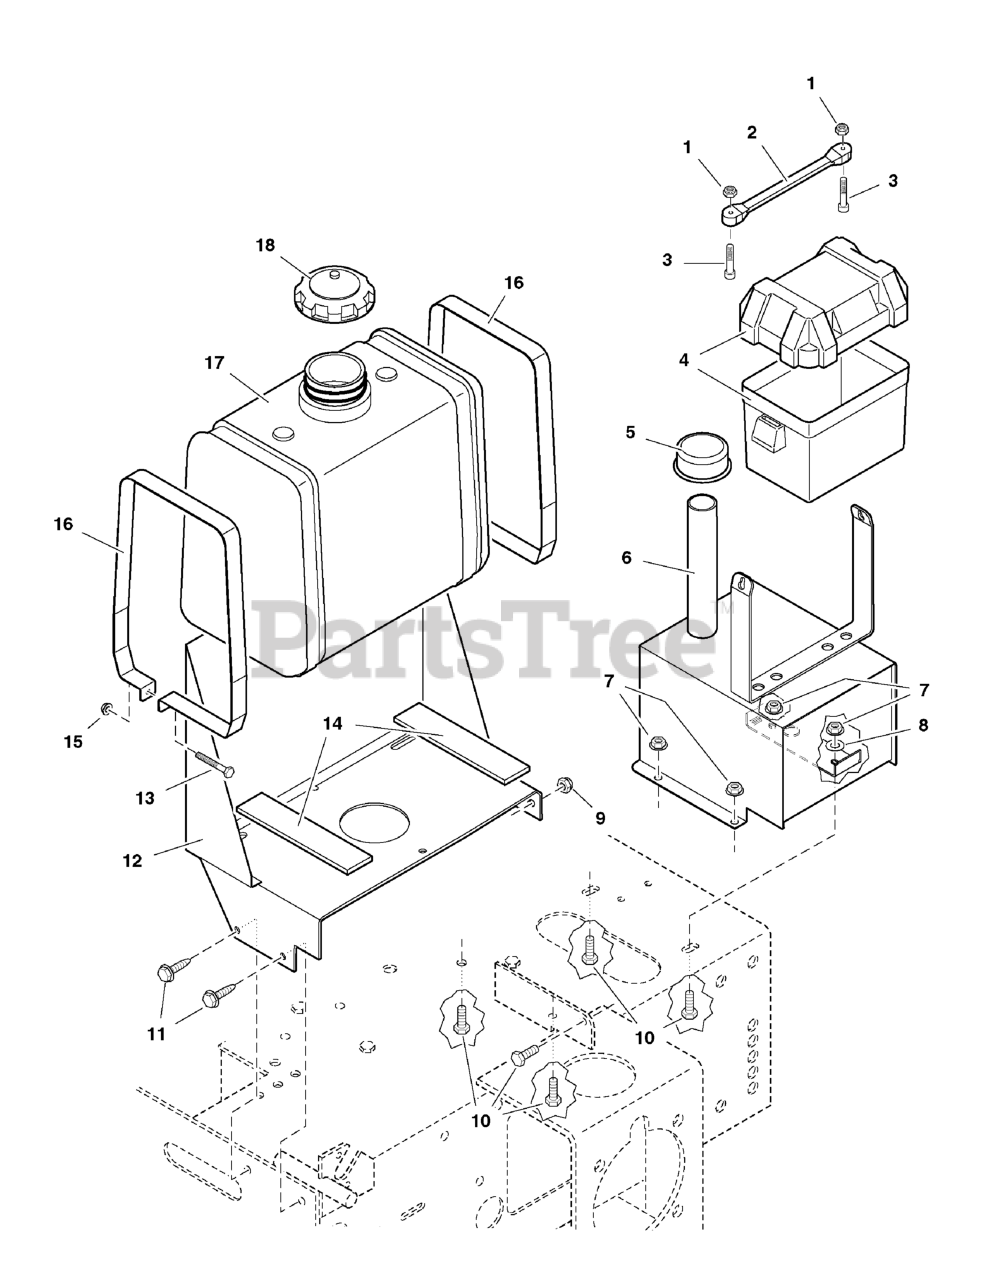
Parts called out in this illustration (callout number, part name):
1	NUT, #10-24 Hex Nylon Lock
2	RUBBER STRAP
3	SCREW, #10-24 X 1 RS, CZ
4	BATTERY BOX
5	BREATHER
6	HYDRO TANK ASSEMBLY, Complete
6	HYDRO TANK WELDMENT
6	FOIL TAPE
7	NUT, 5/16-18 HEX SERRATED FLANGE (SMALL)
8	WASHER, 5/16" SAE
9	NUT, 5/16-18 Hex Nylon Lock
10	BOLT, 5/16-18 X 3/4 GD5
11	BOLT, Self Tapping, 5/16-18 x 3/4
12	FUEL TANK MOUNT
13	BOLT, 1/4-20 X 1-1/2
14	RUBBER PAD
15	NUT, 1/4-20 HEX SERR. FLANGE
16	FUEL TANK STRAP
17	TANK, FUEL, PLASTIC, 6 GALLON W/ FUEL LINE
18	CAP, GASOLINE, VENTED
